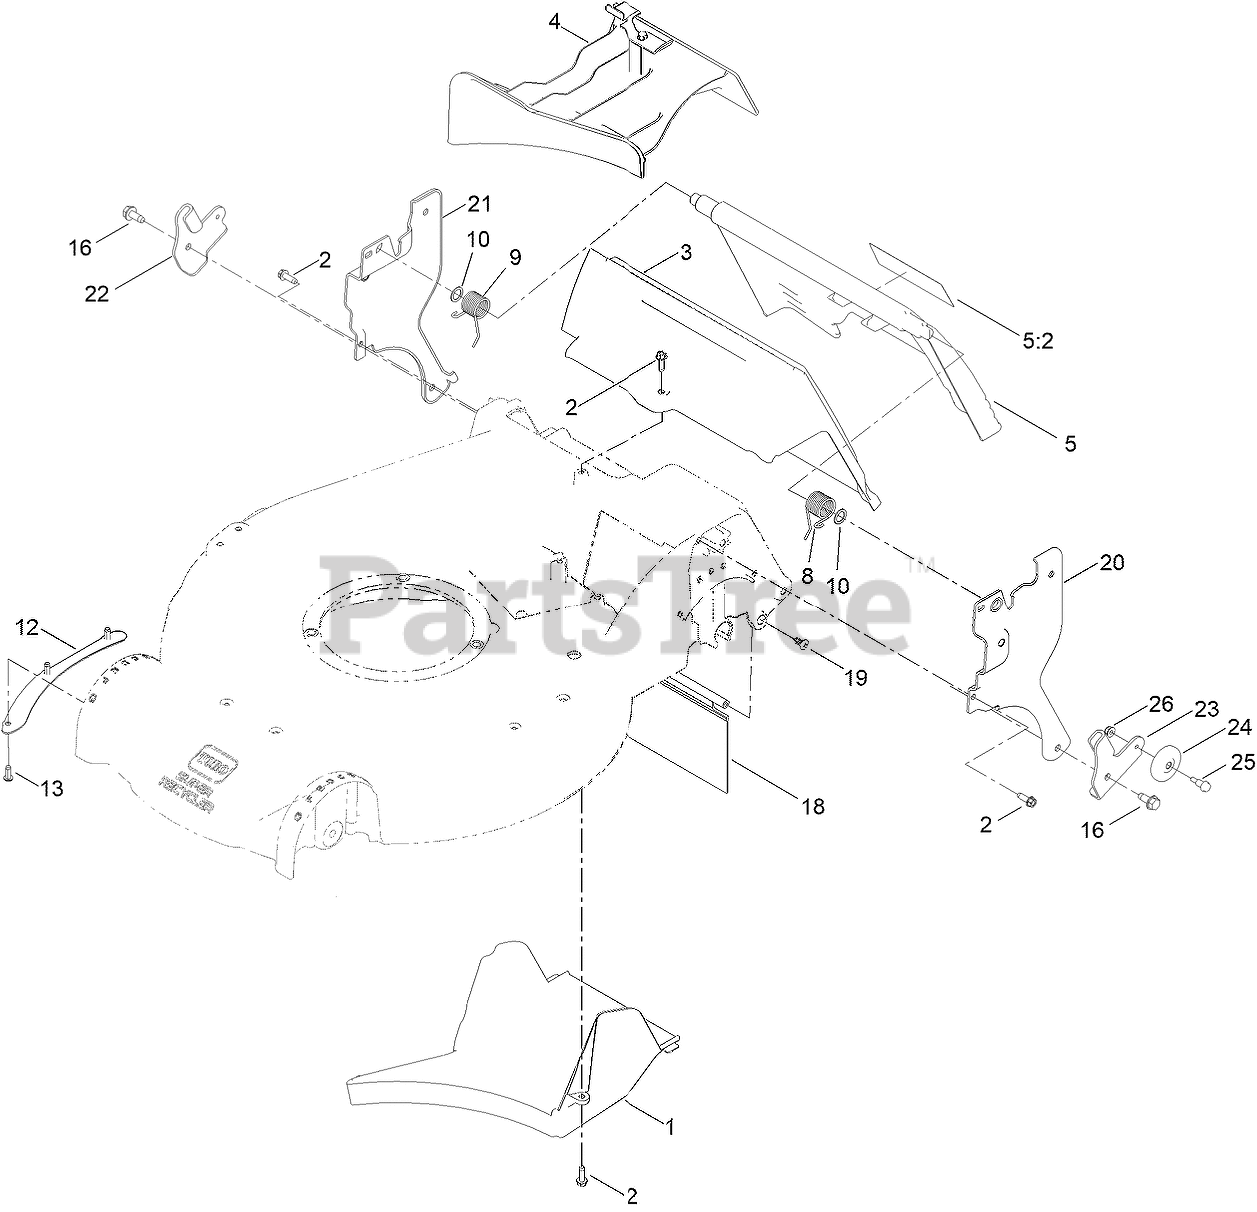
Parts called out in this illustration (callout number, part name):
1	TUNNEL-DISCHARGE
2	SCREW-HWHTF
4	MULCH PLUG ASM
5	REAR DOOR ASM
5:2	DECAL-WARNING
8	SPRING-TORSION
9	SPRING-TORSION
10	WASHER-NYLON
12	LIP-HOUSING
13	SCREW
16	SCREW-HWHTF
18	SHIELD-TRAILING
19	SCREW-PTH
20	PLATE-HANDLE, LH
21	PLATE-HANDLE, RH
22	BRACKET-SMARTSTOW, RH
23	BRACKET-SMARTSTOW, LH
24	WHEEL-SWEEP
25	SCREW-SHOULDER
26	NUT-HF
